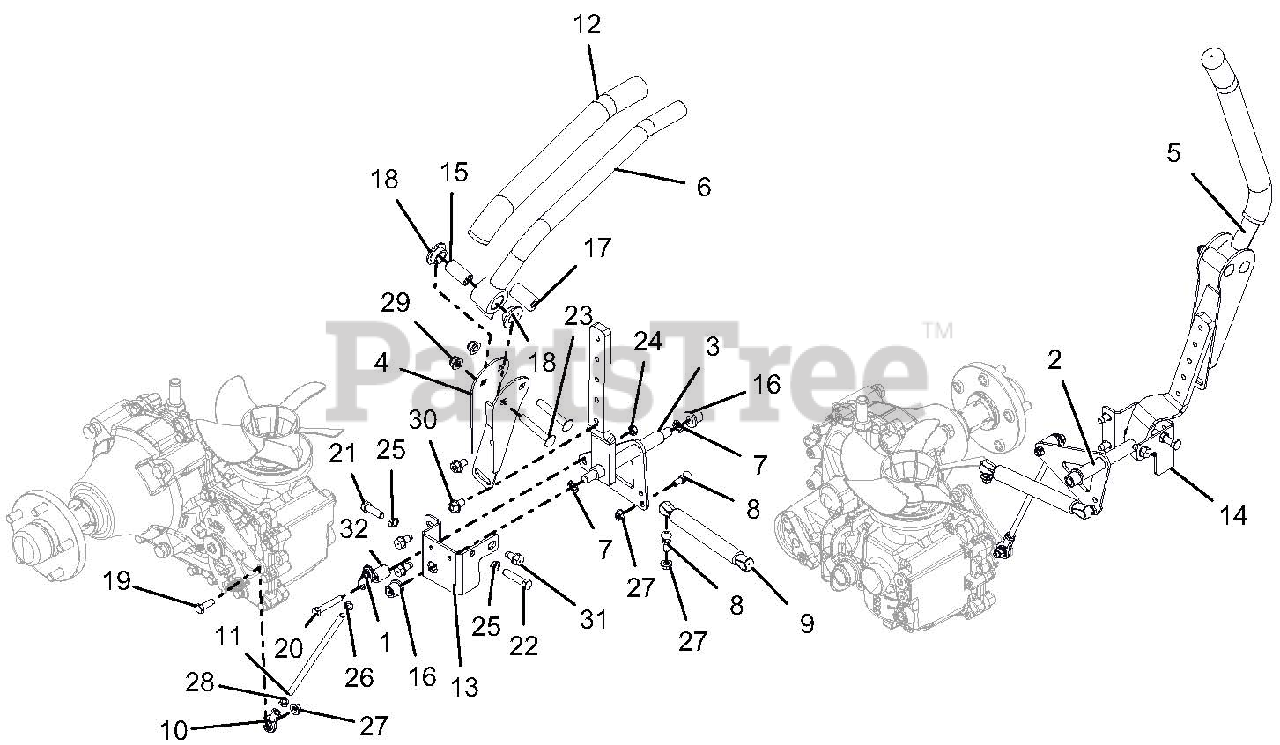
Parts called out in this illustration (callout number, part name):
1	ALIGNABALL, 5/16 RH THREAD
2	WLDMT, LH LOWER CONTROL ARM
3	WLDMT, RH LOWER CONTROL ARM
4	UPPER ADJ CNTRL ARM WLDMT- BLK
5	WLDMT, LH DRIVE CONTROL HANDLE
6	WLDMT, RH DRIVE CONTROL HANDLE
7	WAVE WASHER .531X.781X.125FH
8	STUD- BALL
9	DAMPER
10	ALIGNABALL, 5/16 LH THREAD
11	ROD, STEERING
12	GRIP, HANDLEBAR
13	BRACKET, STEERING STOP, RH
14	BRACKET, STEERING STOP, LH
15	SPACER, STEERING ARM
16	BHSG-FLG .500X.750X.750X.125
17	BSHG, ECCENTRIC.406X.875X1.625
18	BSHG-FLG .762X1.48X.44 NYL
19	@BLT-HEX .31-18X1.00 GR5 YWZC
20	@BLT-HEX .31-18X2.00 GR5 YWZC
21	@BLT-HEX .38-16X1.25 GR5 YWZC
22	BLT-HEX .375-16X1.750 FTD YWZC
23	BLT-RDHDSQSHK, 38-16X2.50 G5YZ
24	@NUT-LK-CTR .31-18 YWZC
25	NUT-HEX-JAM .375-16 YWZC
26	NUT-JAM .31-24 YWZC
27	@NUT-LK-TOP-FLG .31-18 YWZC
28	NUT-JAM LH .31-24 YWZC
29	@NUT-LK-NYL-FLG .38-16 YWZC
30	BLT-SERHFWH .38-16X.62 YWZC
31	@SCR-TAP .38-16X.75 HWH TR YWZ
32	ECCENTRIC
